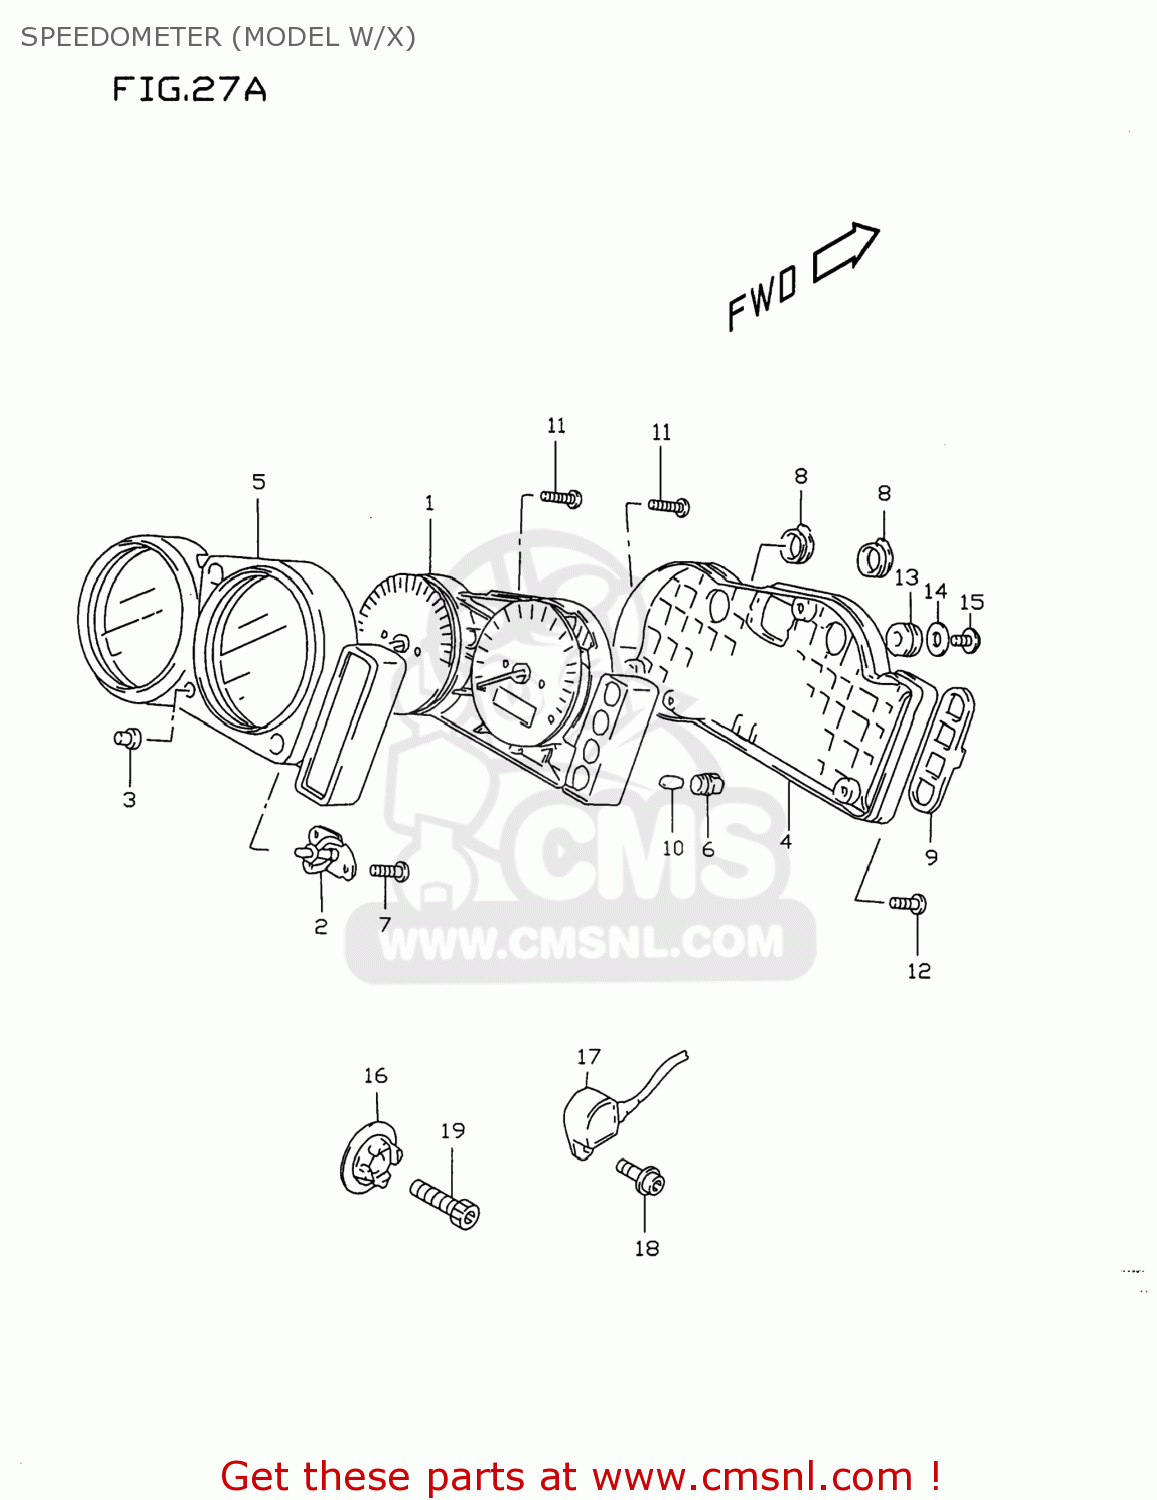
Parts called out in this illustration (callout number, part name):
1	SPEED & TACHOMETER(KILO)
2	ATTACHMENT,SWITCH
3	SWITCH,GUM
4	CASE ASSY
5	VISOR,METER
6	SOCKET(T:6.5)
7	SCREW(3X10)
8	CAP,BLIND NO.1
9	CAP,BLIND NO.2
10	BULB(12V1.7W,T6.5)
11	SCREW
12	SCREW
13	CUSHION,METER
14	WASHER(5.5X16X1.2)
15	SCREW
16	ROTOR,SPEED
17	SENSOR,SPEED
18	BOLT
19	BOLT
